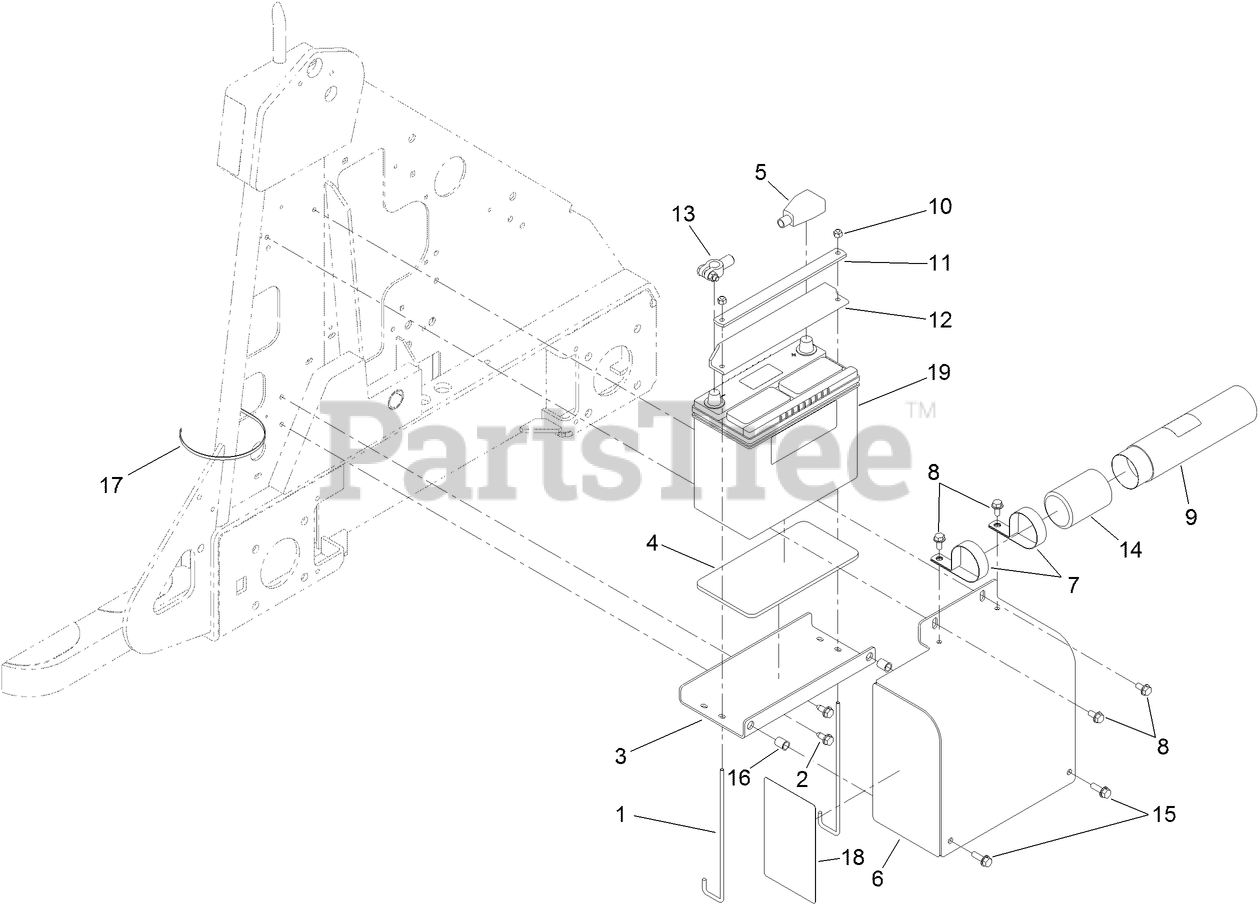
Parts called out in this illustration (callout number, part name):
1	RETAINER-BATTERY
2	SCREW-HWHTF
3	MOUNT-BATTERY
4	PAD-BATTERY
5	CABLE-BATTERY, POSITIVE
6	COVER-BATTERY
7	CLAMP-R
8	SCREW-HWHTF
9	TUBE-MANUAL
10	NUT-LOCK, NI
11	RETAINER-BATTERY
12	RETAINER-BATTERY
13	CABLE-BATTERY, NEGATIVE
14	CAP-HOUSING
15	SCREW-HHF
16	NUT-CLINCH
17	TIE-CABLE
18	DECAL-SERVICE
18	DECAL-SERVICE, FRENCH
18	DECAL-SERVICE, GERMAN
18	DECAL-SERVICE, SPANISH
18	DECAL-SERVICE, ITALIAN
18	DECAL-SERVICE, DUTCH
18	DECAL-SERVICE, POLISH
18	DECAL-SERVICE, RUSSIAN
18	DECAL-SERVICE, SLOVAKIAN
19	BATTERY-DRY
